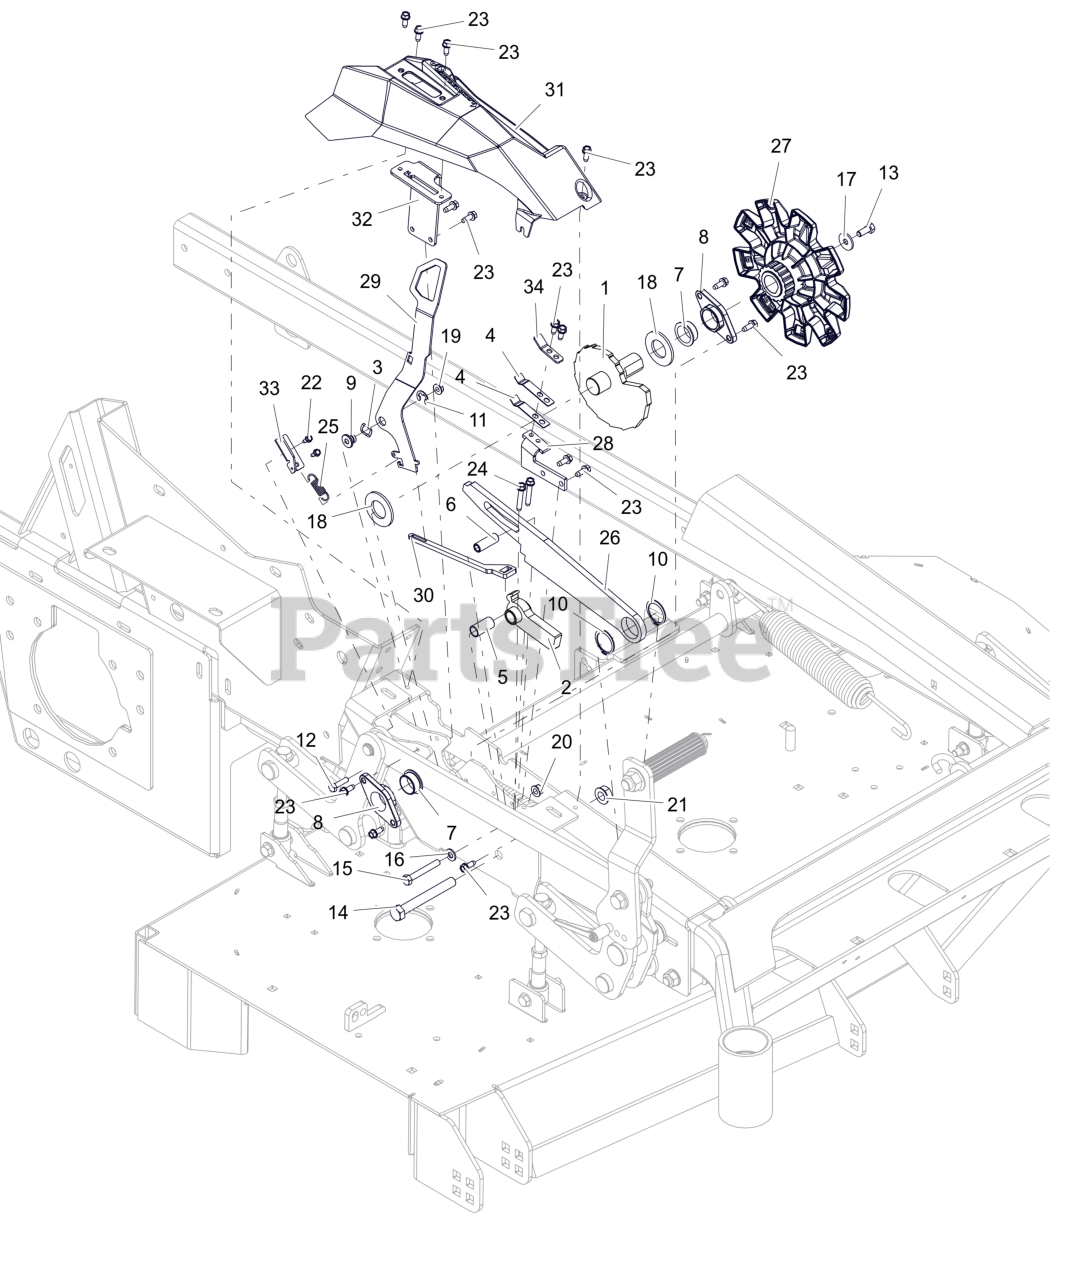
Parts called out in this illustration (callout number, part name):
1	WLDMT, HOC
2	WLDMT, TRANSPORT LOCK PAWL (BLACK)
3	WAVE WASHER .531X.781X.125FH
4	ARM, HOC DETENT
5	SPCR-SLV .531 X .625 X 1.25
6	SPCR, SLV .328 X .439 X 1.381
7	BSHG-FLG 1.0X1.125X.50X1.375 R
8	BSHG, 1.000X1.375X.650
9	BSHG FLANGED .270 X .500 X .468 X .75
10	RG-RET-EXT 1.25 X .050
11	RG-RTNG-EXT .500X.042 (E)
12	BLT,HEX .25-20X1.00 G5 ZCC
13	BLT,HEX .31-18X.75 G5 ZCC
14	BLT, HEX .50-13X4.00 G5 ZCC
15	BLT, HEX .31-18X2.25 G5 ZCC
16	WSHR,FLT .344X.688X.065 ZCC
17	WSHR,FLT .328X1.00X.094 ZCC
18	WSHR-FL-STL 1.062X2X0.134 ZCC
19	NUT-LK-CTR-FLG .25-20 ZC120
20	NUT,LK-CTR-FLG .31-18 GF ZCC
21	NUT-LK-CTR-FLG .500-13 GG ZCC
22	SCR,TAP #10-24X.50 HWH TR ZCC
23	SCR,TAP .25-20X.625 HWH ZCC
24	SCR-TAP .25-20X1.50 HWH ZCC
25	SG-TENS .063X.44X1.56
26	ARM, HOC LINK (BLACK)
27	WHEEL, HOC INDEX
28	BRKT, HOC DETENT MTG (BLACK)
29	LEVER, TRANSPORT LOCK (BLACK)
30	ARM, TRANSPORT LOCK (BLACK)
31	COVER, TRANSPORT LOCK
32	PLATE, TRANSPORT LOCK POSITION (BLACK)
33	BRKT, SPRG (BLACK)
34	TAB, REINFORCING (BLACK)
